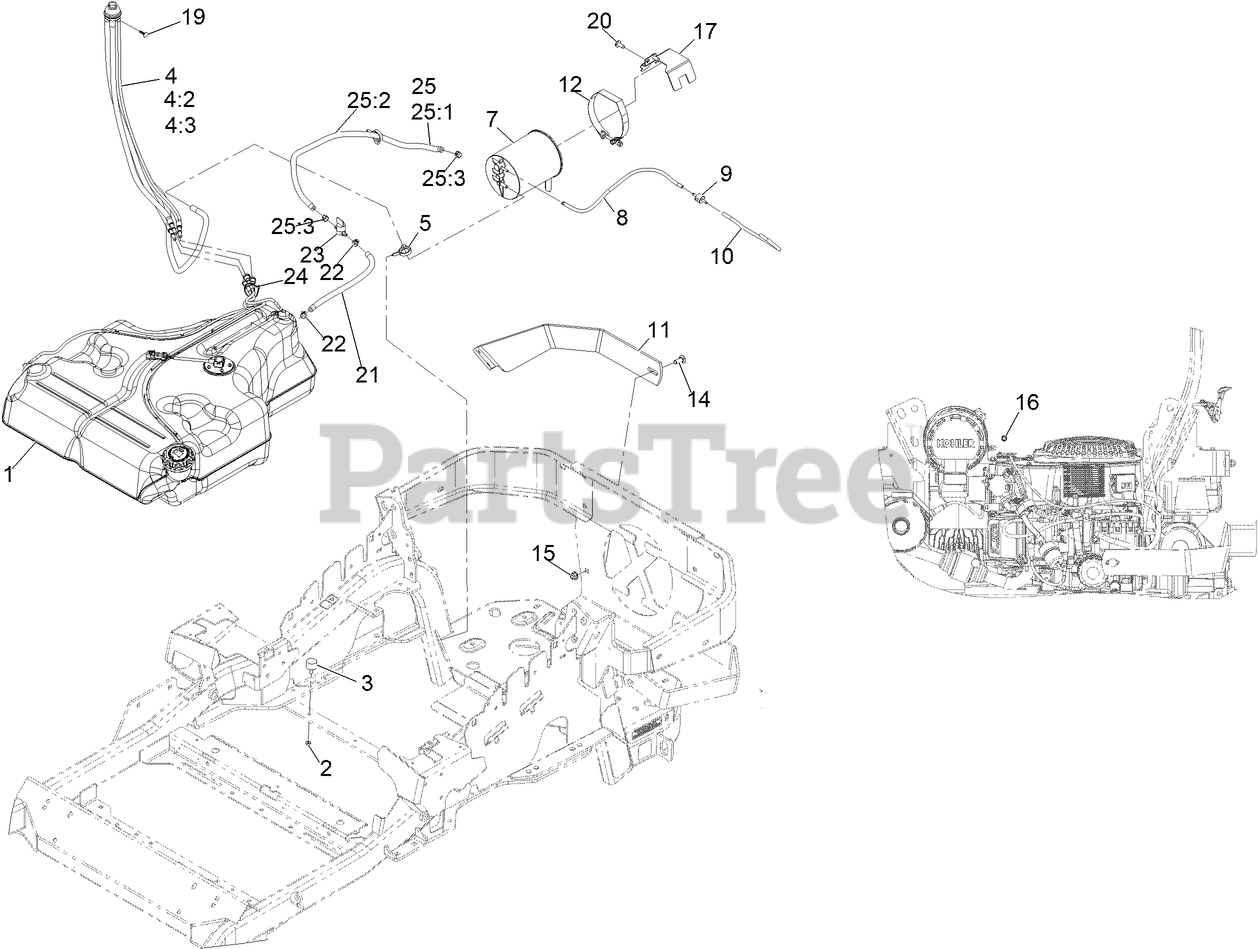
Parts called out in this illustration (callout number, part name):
1	FUEL TANK ASM
2	NUT-JAM
4	FUEL MANIFOLD VENT ASM
4:2	HOSE-FUEL
4:3	HOSE-FUEL
5	CLAMP-HOSE
7	CANISTER-CARBON, 1200CC
8	HOSE-VENT, FORMED
9	VALVE-CHECK, VACUUM
10	HOSE-VENT, FORMED
11	STRAP-GUARD
12	CLAMP, T-BOLT
14	SCREW-CARR
15	NUT-HF, NI
16	PLUG-PORT
17	Mount-Canister
19	PLUG-PLASTIC
21	HOSE-FUEL
22	CLAMP-HOSE
23	VALVE-FUEL
24	TIE-CABLE
25	FUEL LINE ASM
25:1	HOSE-FUEL
25:2	SLEEVE, THERMAL
25:3	CLAMP-HOSE
